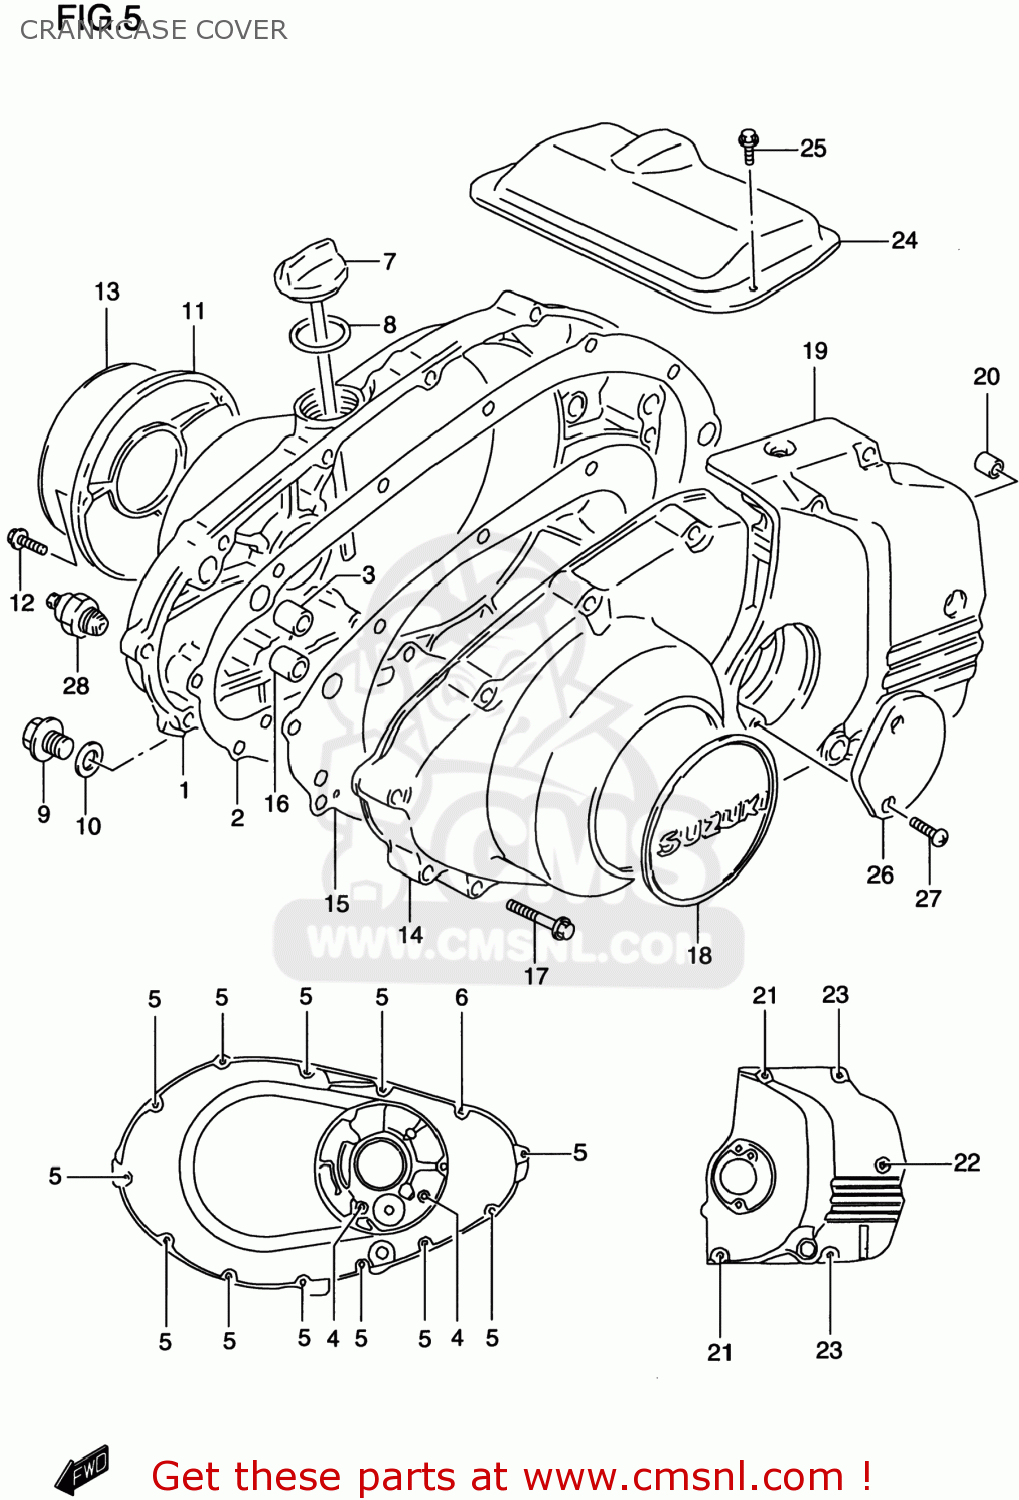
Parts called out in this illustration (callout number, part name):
1	COVER,CLUTCH
2	GASKET,CLUTCH COVER (NAS)
3	PIN
4	BOLT
5	BOLT
6	BOLT
7	GAUGE,OIL LEVEL
8	O RING(D:3.1,ID:26.4)
9	PLUG (14X12)
10	GASKET(13.8X18.8X4.8) (NAS)
11	COVER,CONTACT BREAKER
12	BOLT
13	EMBLEM,CONTACT BREAKER COVER
14	COVER,MAGNETO
15	GASKET,MAGNETO COVER (NAS)
16	PIN
17	BOLT
18	EMBLEM,CONTACT BREAKER COVER
19	COVER,ENGINE SPROCKET
20	PIN
21	BOLT
22	BOLT
23	BOLT
24	COVER,STARTER MOTOR
25	BOLT
26	CAP,CLUTCH RELEASE ADJUST
27	SCREW
28	SWITCH ASSEMBLY,OIL PRESSURE
